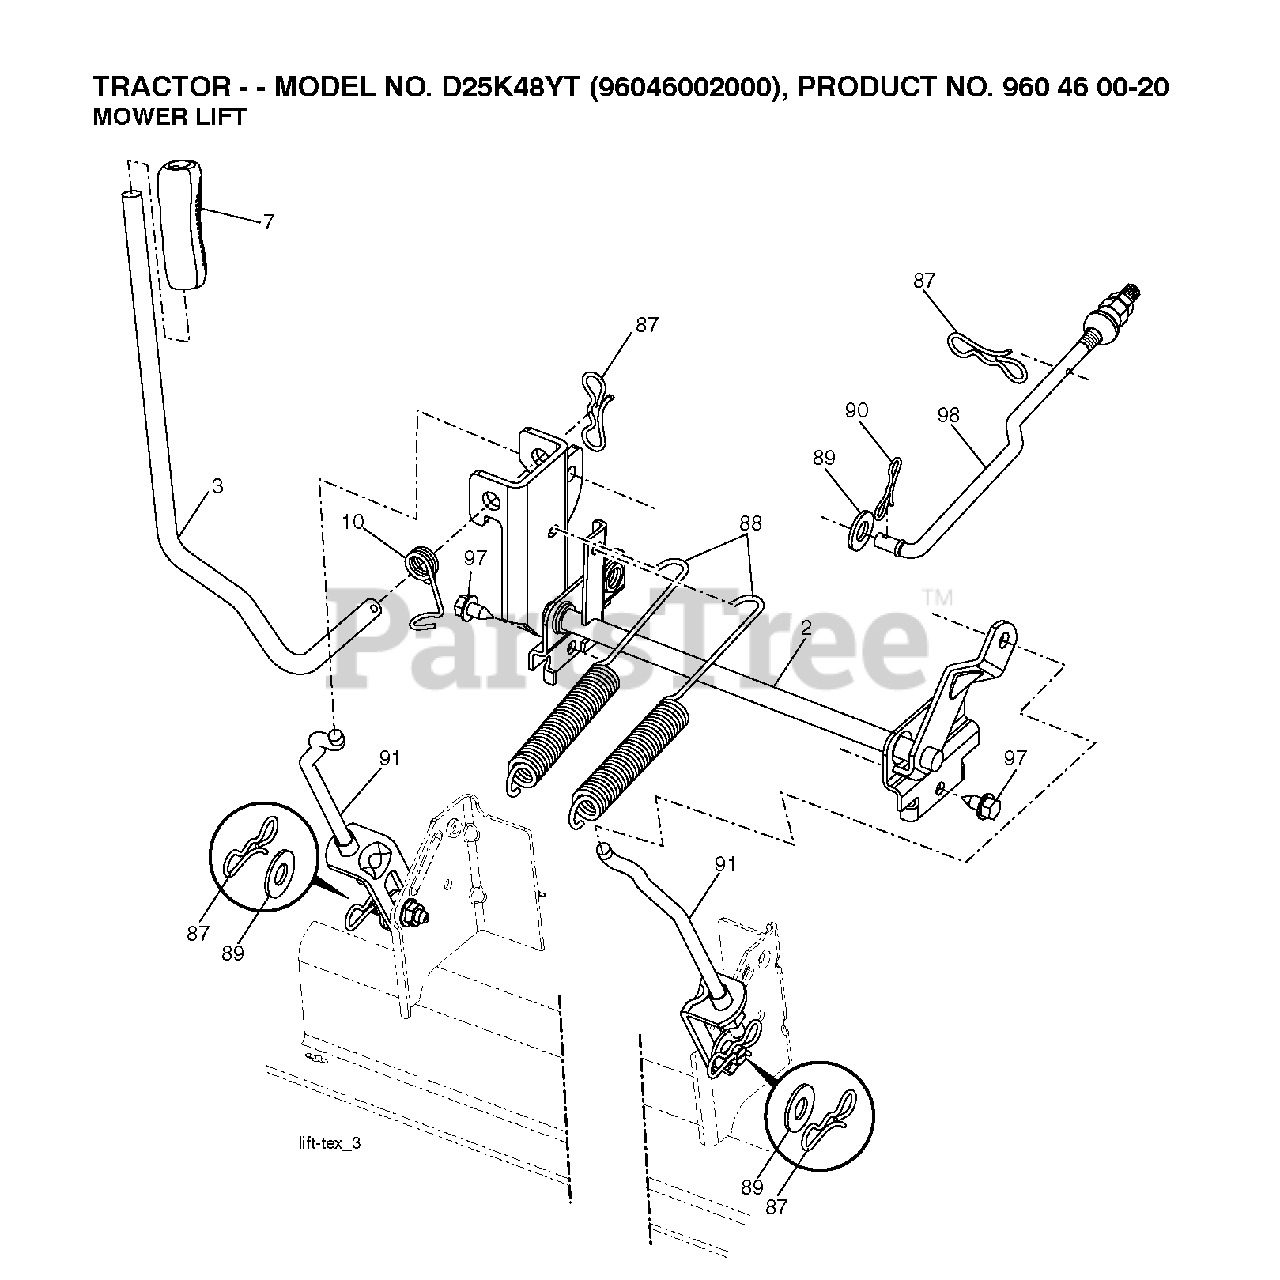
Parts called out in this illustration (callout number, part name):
2	SHAFT.ASM.CROSS.LIFT
3	LEVER.LIFT.HANDLE.LT
7	GRIP.HANDLE.LIFT.PVC.BLACK
10	SPRING.TORSION.LIFT.HANDLE
87	PIN.COTTER.7/16.BOW TI.
88	SPRING.LIFT.ASSIST
89	WASHER.CLEAR.ZINC
90	PIN.COTTER.5/16.BOW TI
91	LINK.ASM.LIFT.54"TG
97	SCREW, 3/8-16X3/4
98	LINK.ASM.SUSP.FRONT.MWR.10.5
